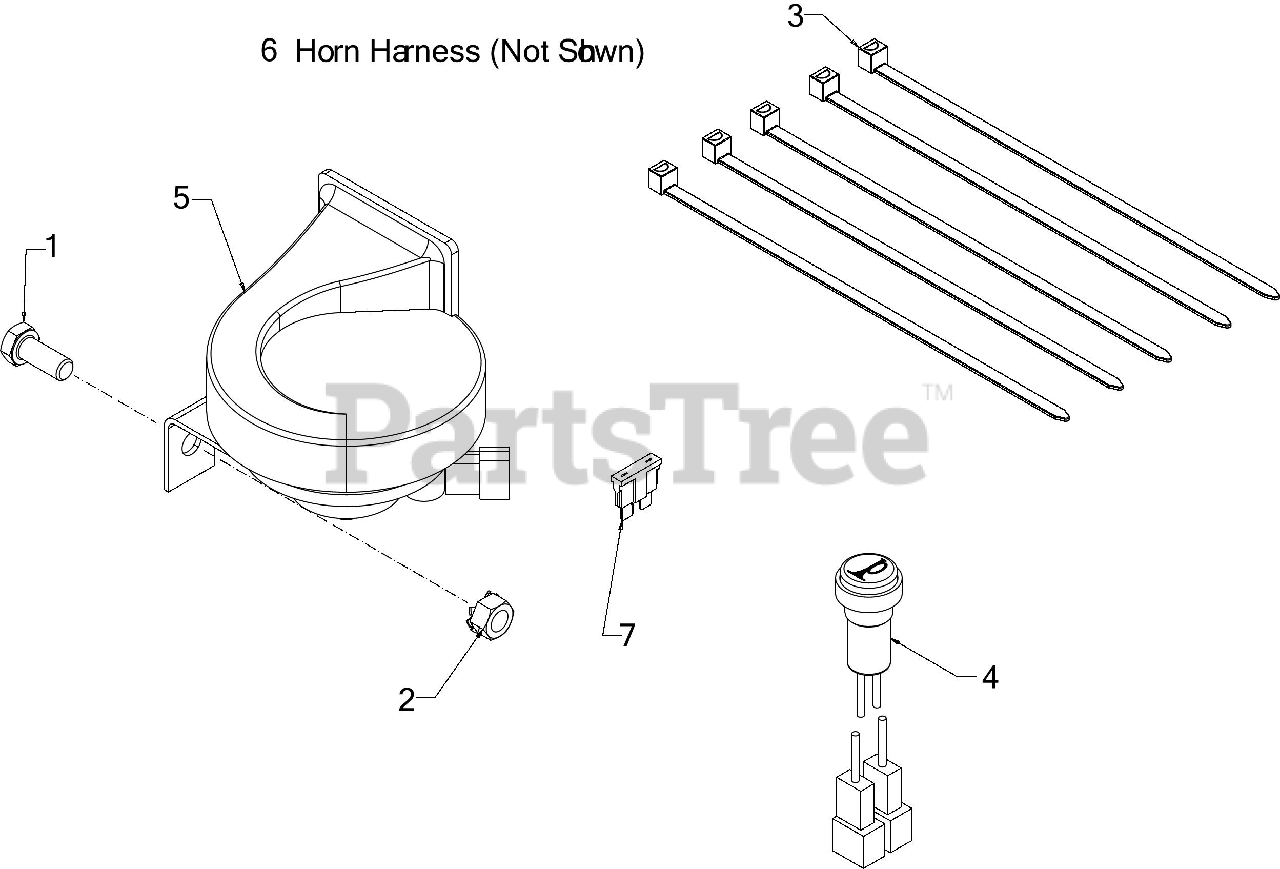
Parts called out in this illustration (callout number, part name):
1	SCREW 5/16-18 x .75 GR5
2	SEMS NUT 5/16-18
3	7" CABLE TIE
4	HORN SWITCH
6	ACCESSORY HARNESS-HORN
7	7.5 AMP FUSE
